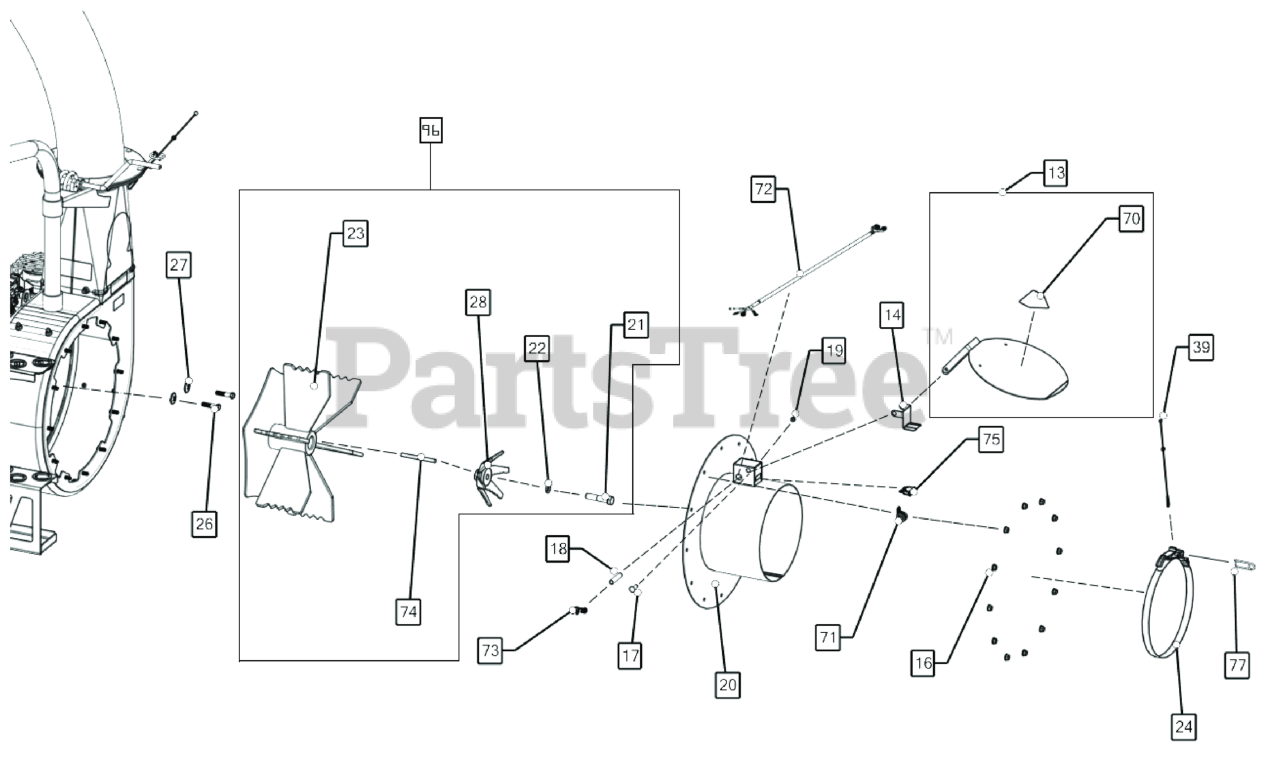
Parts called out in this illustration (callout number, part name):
13	FLAPPER 12"
14	LEVER HOSE SWITCH
16	NUT WASHER FACE
17	BOLT CARRIAGE 5/16"-18 X 3 1/2" ZP
18	SPACER 3/8" X 2 1/2"
19	NUT-HEX-NYLK, FLG .3125-18 ZP
20	INTAKE HOUSING WA 12" DL29
21	SCREWCAP 5/8"-18 X 3.00" ZP GR8
22	WASHER LOCK 5/8" S/T MED
23	IMPELLER WA 20.00" X 1.4375" LOADER DL29
24	CLAMP QUICK RELEASE 12"
26	SCREWCAP 7/16"-14 X 2" GR.5 W/PATCH LOCK
27	WASHER LOCK 7/16" TWISTED TOOTH
28	PIRANHA BLADE WA DL35
39	LANYARD PLASTIC 10"
70	LABEL WARNING OPEI
71	CLAMP ROUTING FUEL LINE
72	HARNESS, WIRING DL
73	STRAIN RELIEF
74	KEY 3/8" SQ. X 4.50"
75	SWITCH, SAFETY INTERLOCK
77	PIN SAFETY
96	IMPELLER WA DL29 SERVICE
